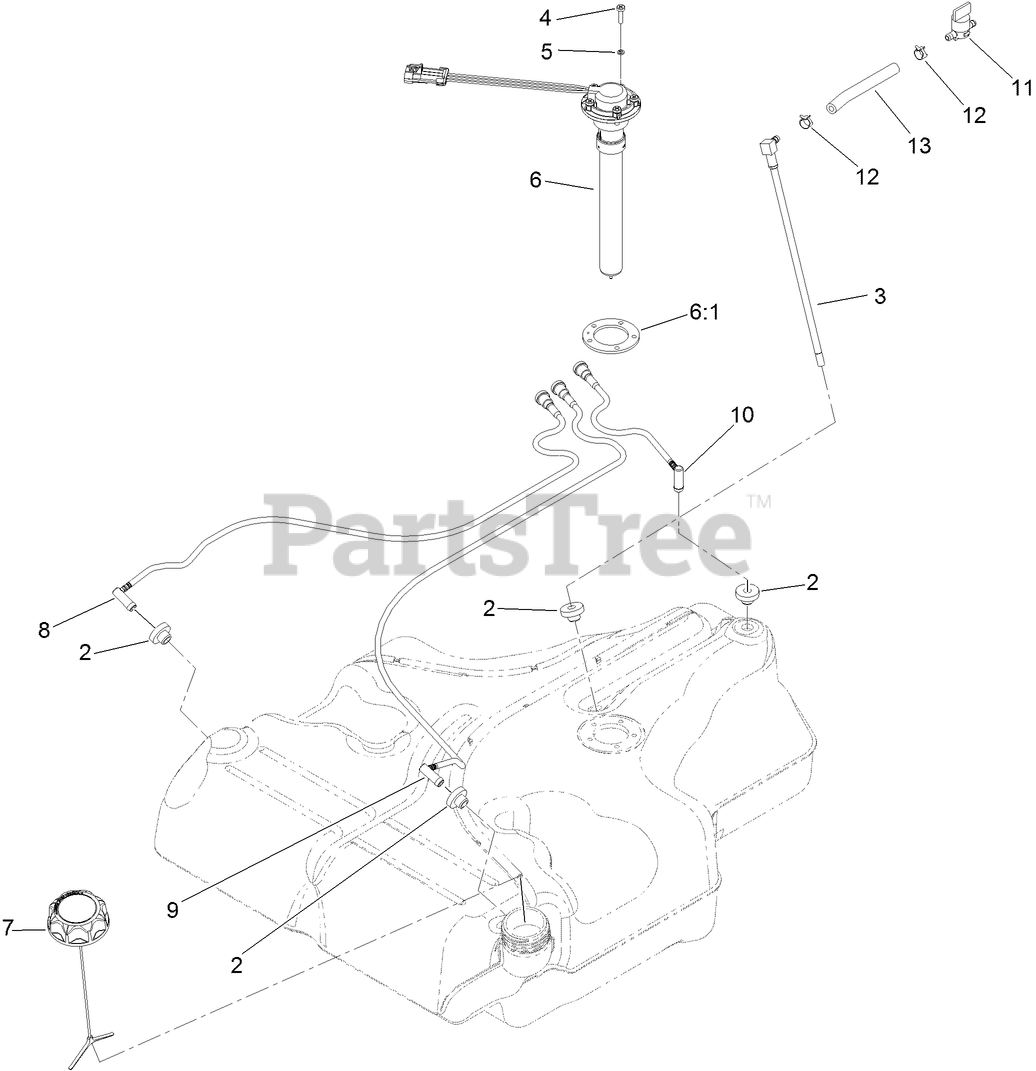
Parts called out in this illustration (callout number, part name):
2	BUSHING
3	FUEL LINE KIT (WITH GROMMET)
4	SCREW-PAN
5	WASHER-LOCK
6	SENDER-LEVEL, FUEL
6:1	GASKET-SENDER, FUEL
7	CAP-FUEL, RATCHETING
8	RH VENT LINE KIT (WITH GROMMET)
9	LH VENT LINE KIT (WITH GROMMET)
10	REAR VENT LINE KIT (WITH GROMMET)
11	VALVE-FUEL
12	CLAMP-HOSE
13	HOSE-FUEL
